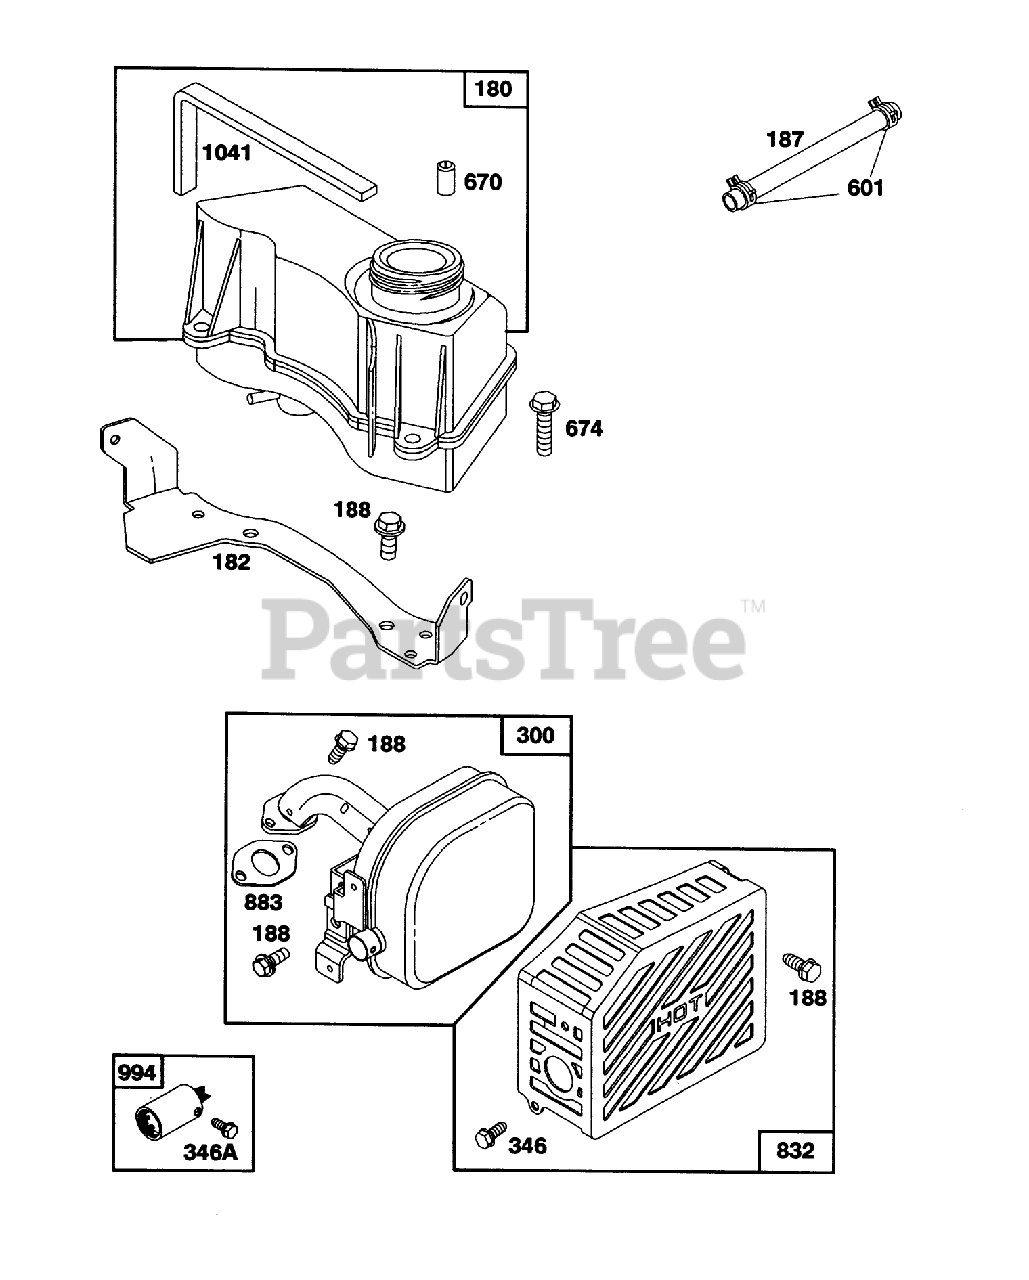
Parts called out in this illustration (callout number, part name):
180	TANK ASSY - FUEL
188	SCREW - SEM
300	MUFFLER - EXHAUST
346	SCREW - SELF-TAPPING
601	CLAMP - CL PIPE
670	SPACER
674	SCREW - HEX HEAD
